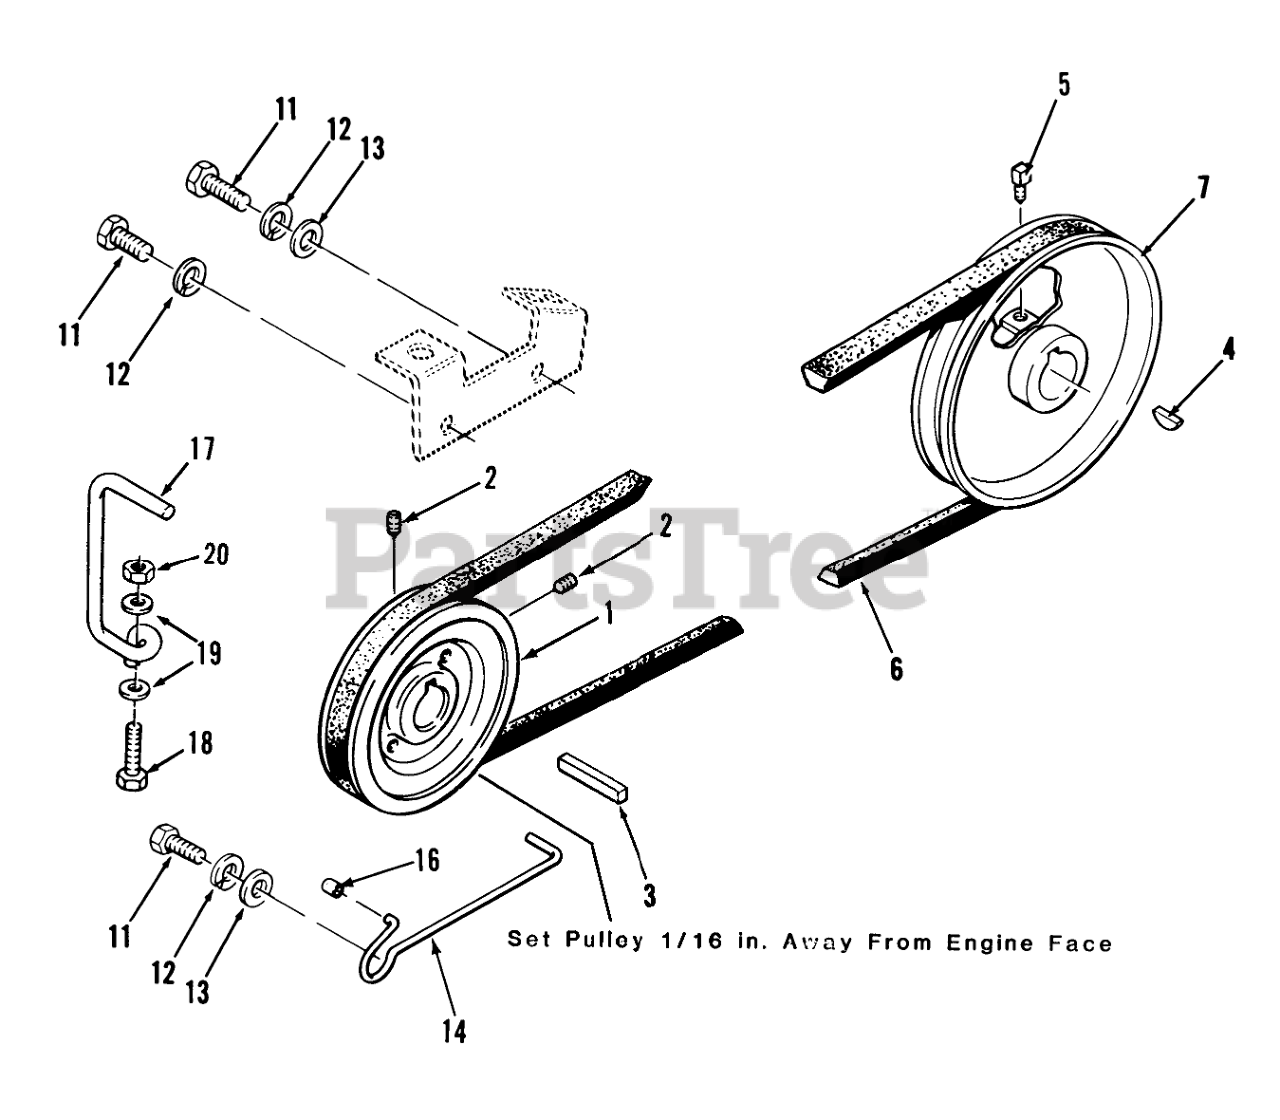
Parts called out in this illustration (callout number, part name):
1	PULLEY
2	Set Screw
4	KEY-HI PRO
5	Set Screw
6	V BELT
6	Belt-Drive
7	PULLEY-TRANSMISSION
11	7/16-14 x 1 1/4 Bolt
12	LOCKWASHER
13	WASHER
14	GUIDE BELT
17	GUIDE-BELT BOTTOM B
18	Bolt
19	Collar
20	Nut
